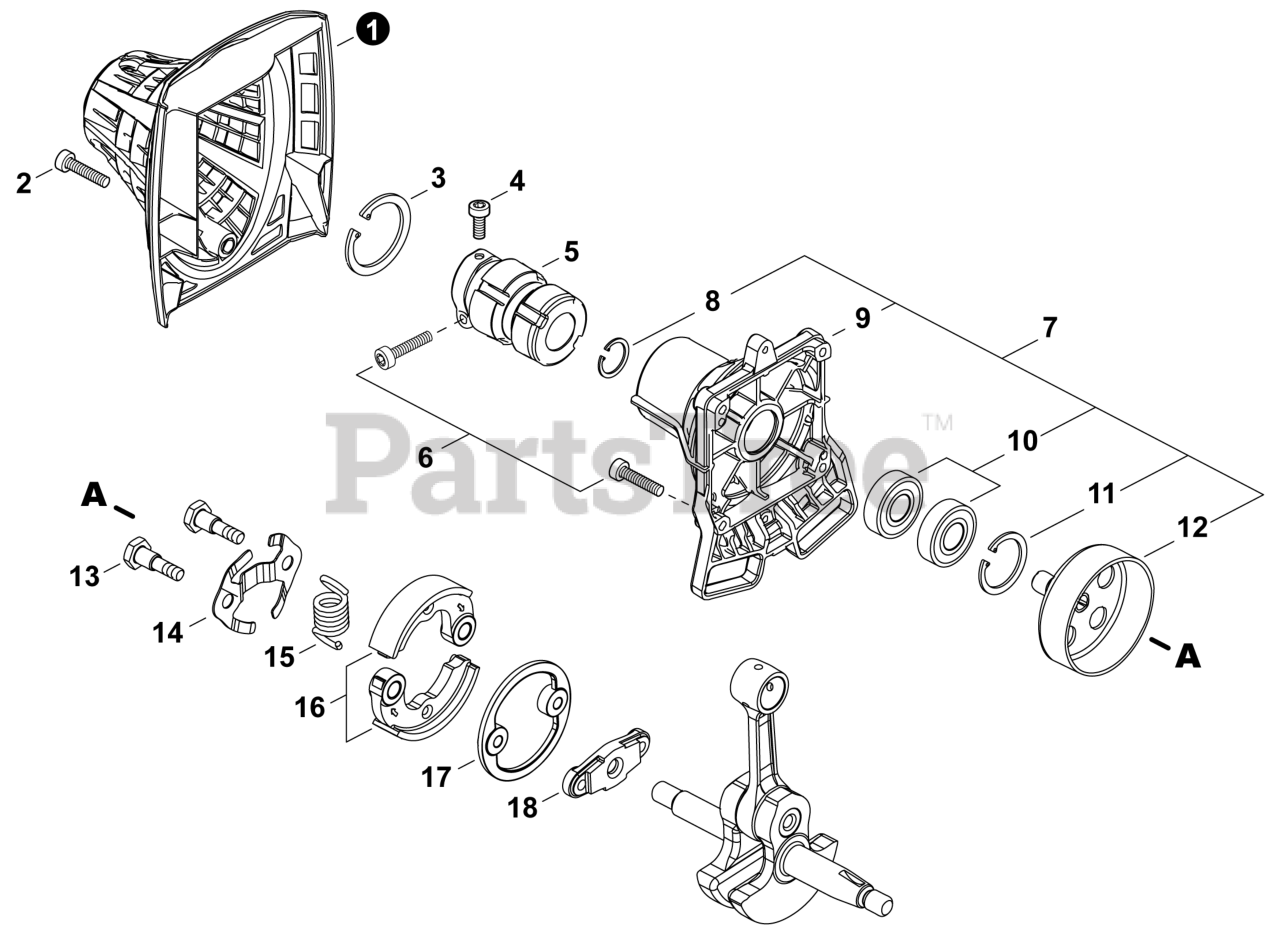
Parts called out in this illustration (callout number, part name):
1	COVER, CLUTCH CASE
2	BOLT, TORX 5×16
3	RING, RETAINING Ø45
4	BOLT, TORX 5×12
5	HOLDER, MAIN PIPE
6	BOLT, TORX 5×25
7	CASE ASSY, CLUTCH
8	RING, SNAP 12
9	CASE, CLUTCH
10	BEARING, BALL 6001
11	RING, SNAP 28
12	DRUM, CLUTCH
13	BOLT, CLUTCH
14	SPRING, FLAT
15	SPRING, CLUTCH
16	CLUTCH SHOE SET
18	HUB, CLUTCH
